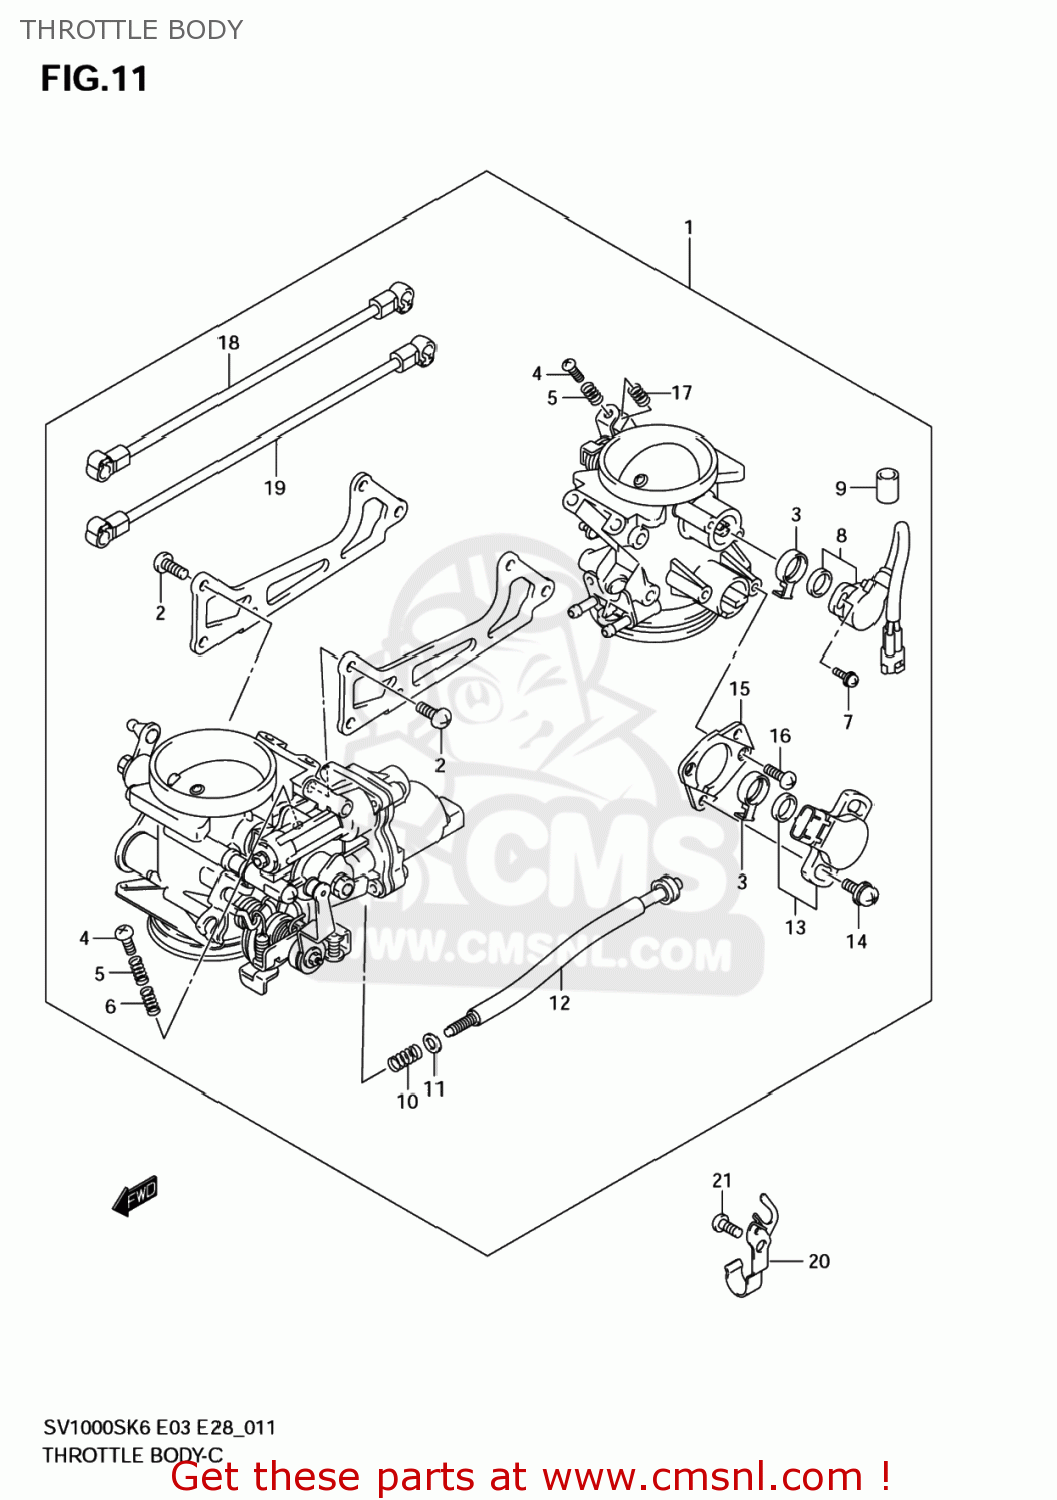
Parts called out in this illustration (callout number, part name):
1	INJECTION ASSY
2	SCREW
3	RING
4	SCREW
5	SPRING
6	SPRING,THROTTLE SCREW
7	SCREW
8	SENSOR ASSY
9	HOSE
10	SPRING
11	WASHER
12	SCREW ASSY,ADJUST
13	SENSOR ASSY,THROTTLE
14	SCREW
15	PLATE
16	SCREW
17	SPRING
18	ROD ASSY
19	ROD ASSY
20	PLATE,IDLE ADJUST
21	BOLT
